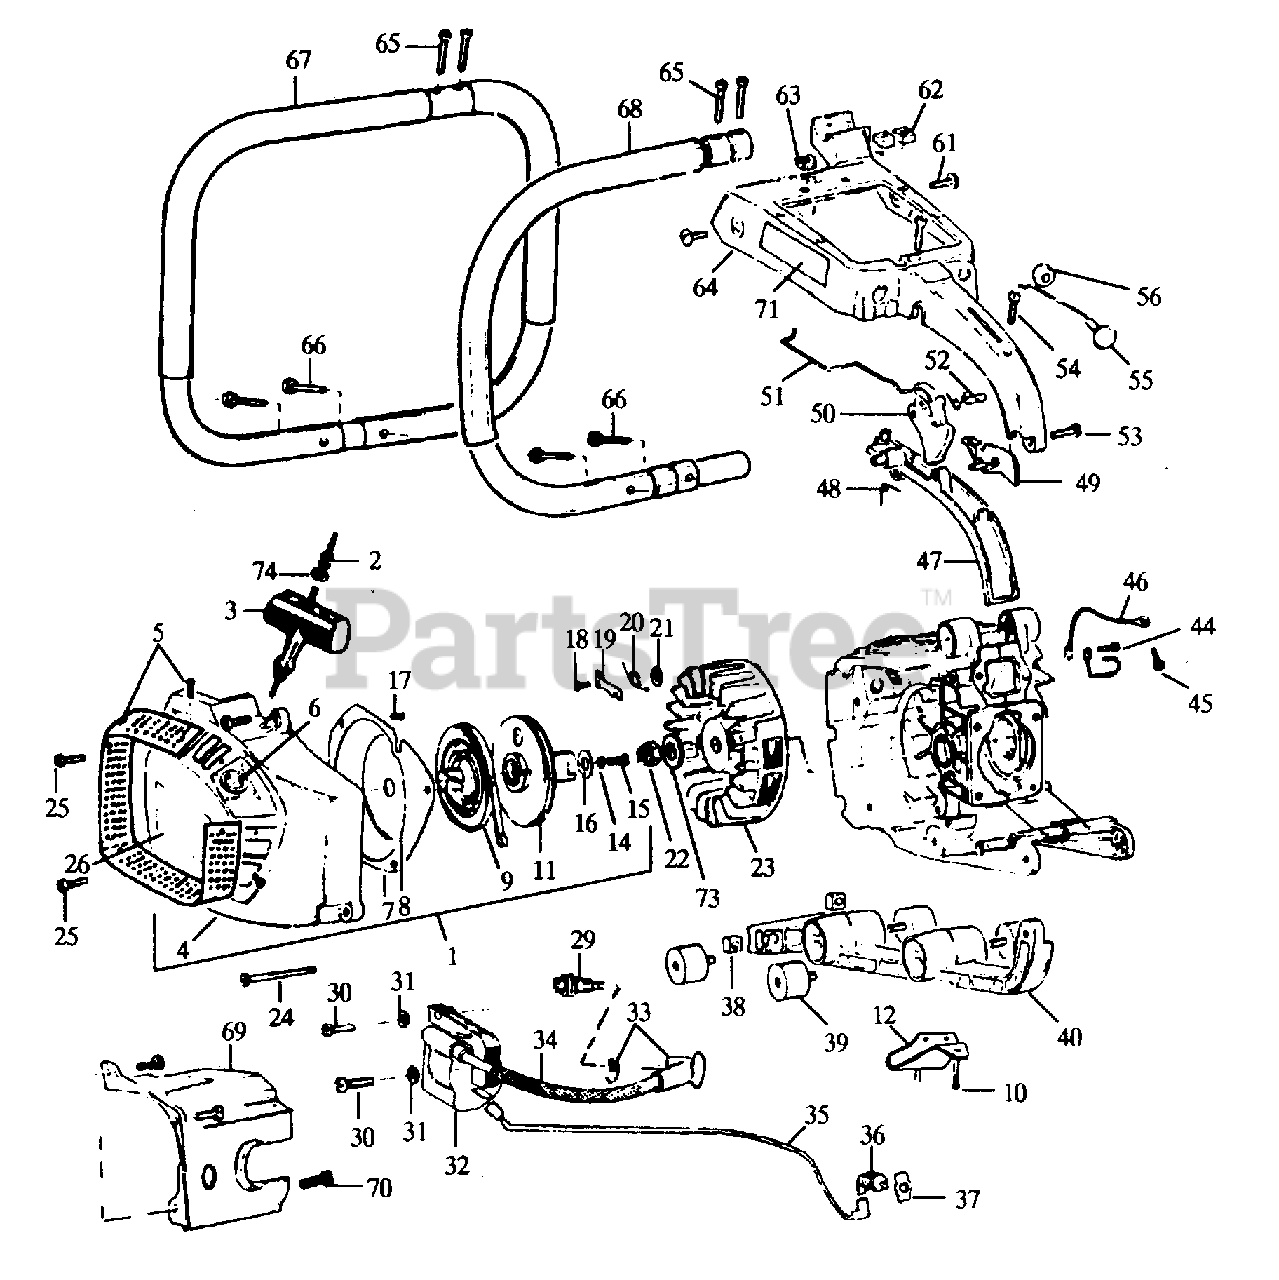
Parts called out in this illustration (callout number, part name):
1	Starter Ass'y.
2	Starter Cord
3	Starter Handle
4	Starter Cover Ass'y.
5	Blower Cover Screen
7	Baffle Plate
9	Rewind Spring
11	Starter Pulley
14	Lockwasher
18	Pawl Pivot
20	Pawl Spring
23	Flywheel
26	Side Decal
29	Spark Plug
32	Module
33	Spark Plug Boot&Clip
35	Switch Wire
36	Grounding Switch
37	Switch Plate
39	Shock Absorber
40	Bottom Frame
44	Plate Screw
45	terminal Screw
46	Ground Wire
47	Lower Grip Ass'y.
48	Throttle Trigger Spring
49	Throttle Lockout Lever
50	Throttle Trigger
51	Throttle Link
52	Throttle Pin
55	ChokeKnob-WireAssy.
64	Top Frame
67	Front Handle - Full
68	Front Handle - Half
69	Cylinder Shroud
71	Top Frame Decal
